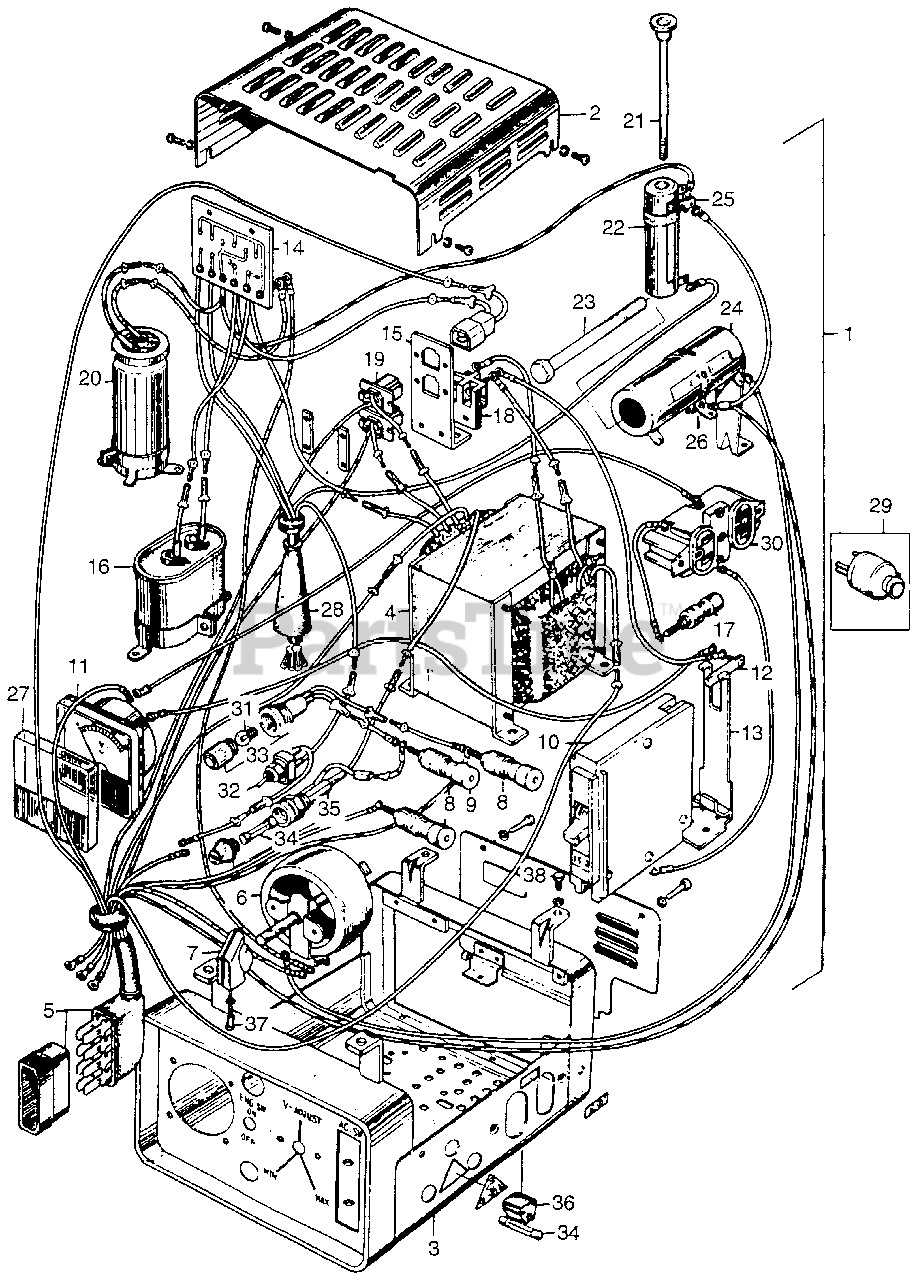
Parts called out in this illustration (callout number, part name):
1	BOX ASSY., CONTROL *R8* (BRIGHT RED)
2	COVER, CONTROL UP *R8* (BRIGHT RED) (NOT AVAILABLE)
3	COVER, CONTROL UNIT (R8)
4	TRANSFORMER ASSY., CURRENT
5	WIRE HARNESS (8P)
6	RESISTOR, VARIABLE (NOT AVAILABLE)
7	KNOB, ADJUSTING
8	TERMINAL, D.C. OUTPUT (+)
9	TERMINAL, D.C. OUTPUT (-)
10	BREAKER, CIRCUIT (12.5A) (NOT AVAILABLE)
11	VOLTMETER ASSY. (150V SCALE)
11	VOLTMETER ASSY.
12	TERMINAL, BREAKER (NOT AVAILABLE)
13	SUPPORT, BREAKER (NOT AVAILABLE)
14	STACK ASSY., DIODE (NOT AVAILABLE)
15	PLATE, CONNECTOR
16	CONDENSER ASSY., B
17	TERMINAL ASSY., GROUND (NOT AVAILABLE)
18	TERMINAL ASSY., FREQUENCY
19	CONNECTOR, FREQUENCY
20	CONDENSER ASSY.
21	BOLT, ADJUSTABLE RESISTOR (NOT AVAILABLE)
22	RESISTOR, ADJUST (NOT AVAILABLE)
23	BOLT, RESISTOR SET
24	RESISTOR SET
25	PLATE, ADJ. (18MM)
26	PLATE, ADJ. (27MM)
27	LENS, METER (NOT AVAILABLE)
28	WIRE HARNESS (4P)
29	PLUG ASSY. (NOT AVAILABLE)
30	RECEPTACLE (15A/125V)
31	BULB, DASH (24V-2W)
32	SWITCH ASSY., ENGINE (NOT AVAILABLE)
33	SOCKET ASSY., PILOT LAMP
35	HOLDER, FUSE (NOT AVAILABLE)
36	SUPPORTER, SPARE FUSE
37	BOLT, KNOB (NOT AVAILABLE)
38	BOLT, HEX. (5X8)
